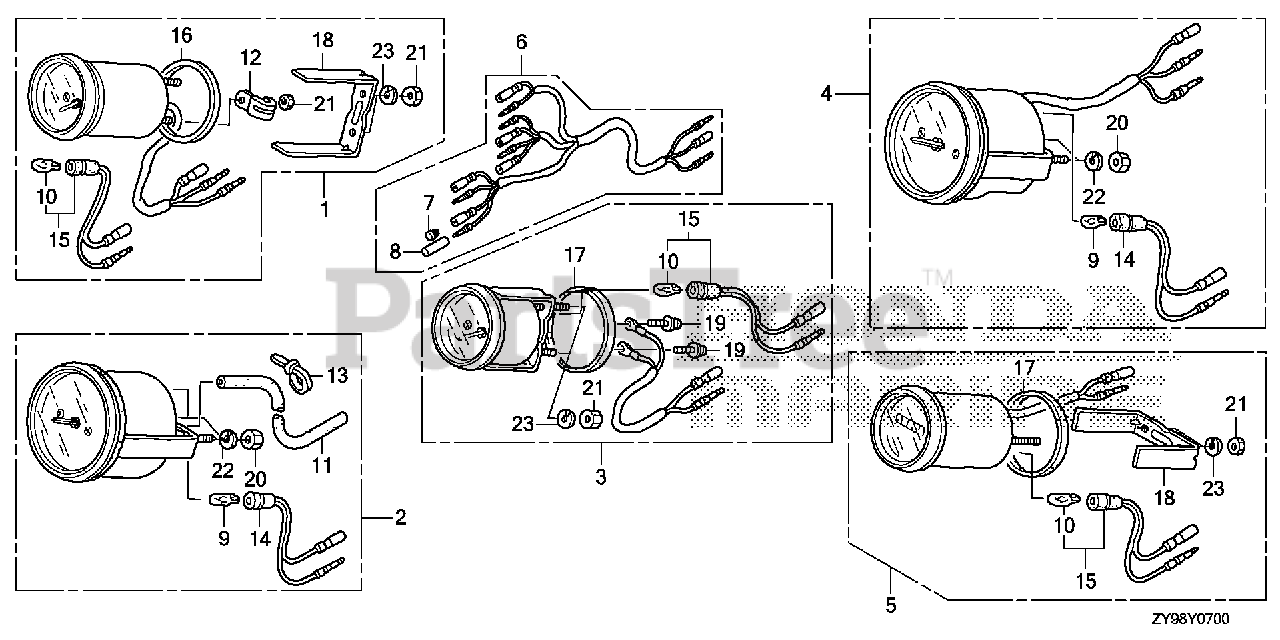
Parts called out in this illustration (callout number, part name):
1	METER KIT, TRIM
1	METER KIT, TRIM (B)
2	SPEEDOMETER KIT
2	SPEEDOMETER KIT (B)
3	METER KIT, VOLT
3	METER KIT, VOLT (B)
4	METER KIT, TACHO
4	METER KIT, TACHO (B)
5	METER KIT, HOUR (NA USE ALT:39700-ZW5-000ZA)
5	METER KIT, HOUR (B) (NA USE ALT:39700-ZW5-000ZA)
6	HARNESS ASSY., METER (B)
7	PLUG, CONNECTOR (INNER)
8	PLUG, CONNECTOR (OUTER)
9	BULB, WEDGE BASE (T10) (12V 1.7W) (STANLEY)
10	BULB, WEDGE BASE (12V 1.7W)
11	TUBE, SPEED METER (4X7X8000)
12	CLAMP
13	BAND, SELF-LOCK
14	SOCKET
15	SOCKET
16	GASKET
17	GASKET
18	BRACKET
19	SCREW-WASHER (3X22)
20	NUT, HEX. (5MM)
21	NUT, HEX. (4MM)
22	WASHER, SPRING (5MM)
23	WASHER, SPRING (4MM)
